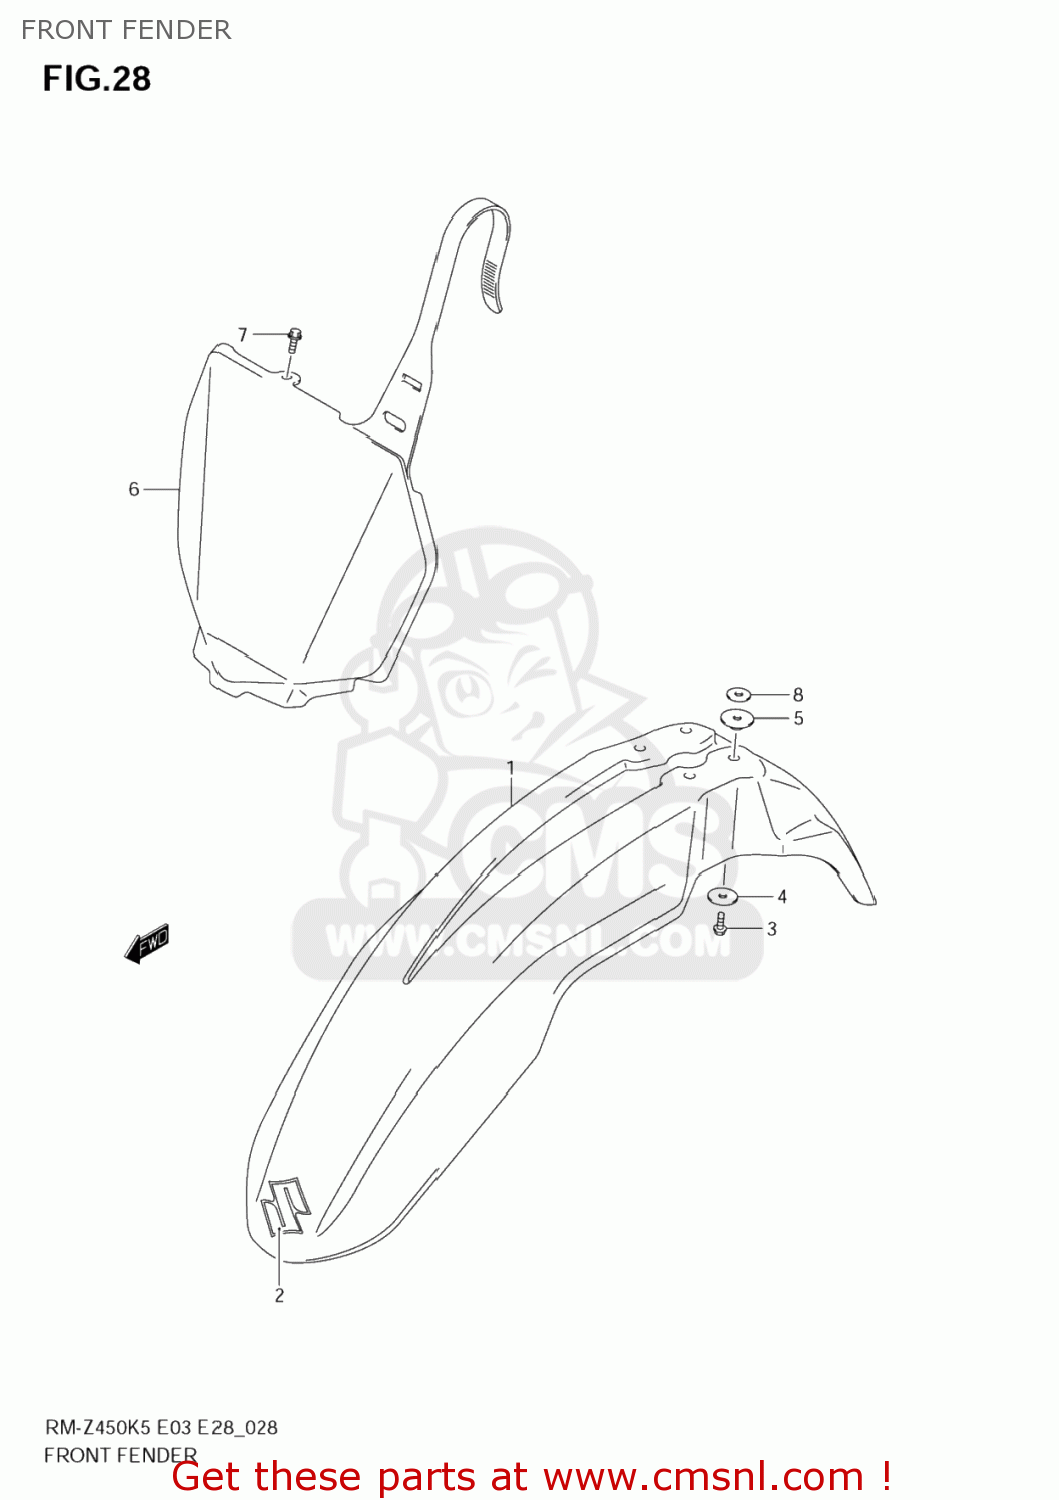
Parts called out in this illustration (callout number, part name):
1	FENDER,FR
2	EMBLEM,S
3	BOLT
4	WASHER(6.5X28X1.6)
5	WASHER
6	PLATE,FRONT NU
7	BOLT(6X12)
8	WASHER(6.5X20X1.2)
